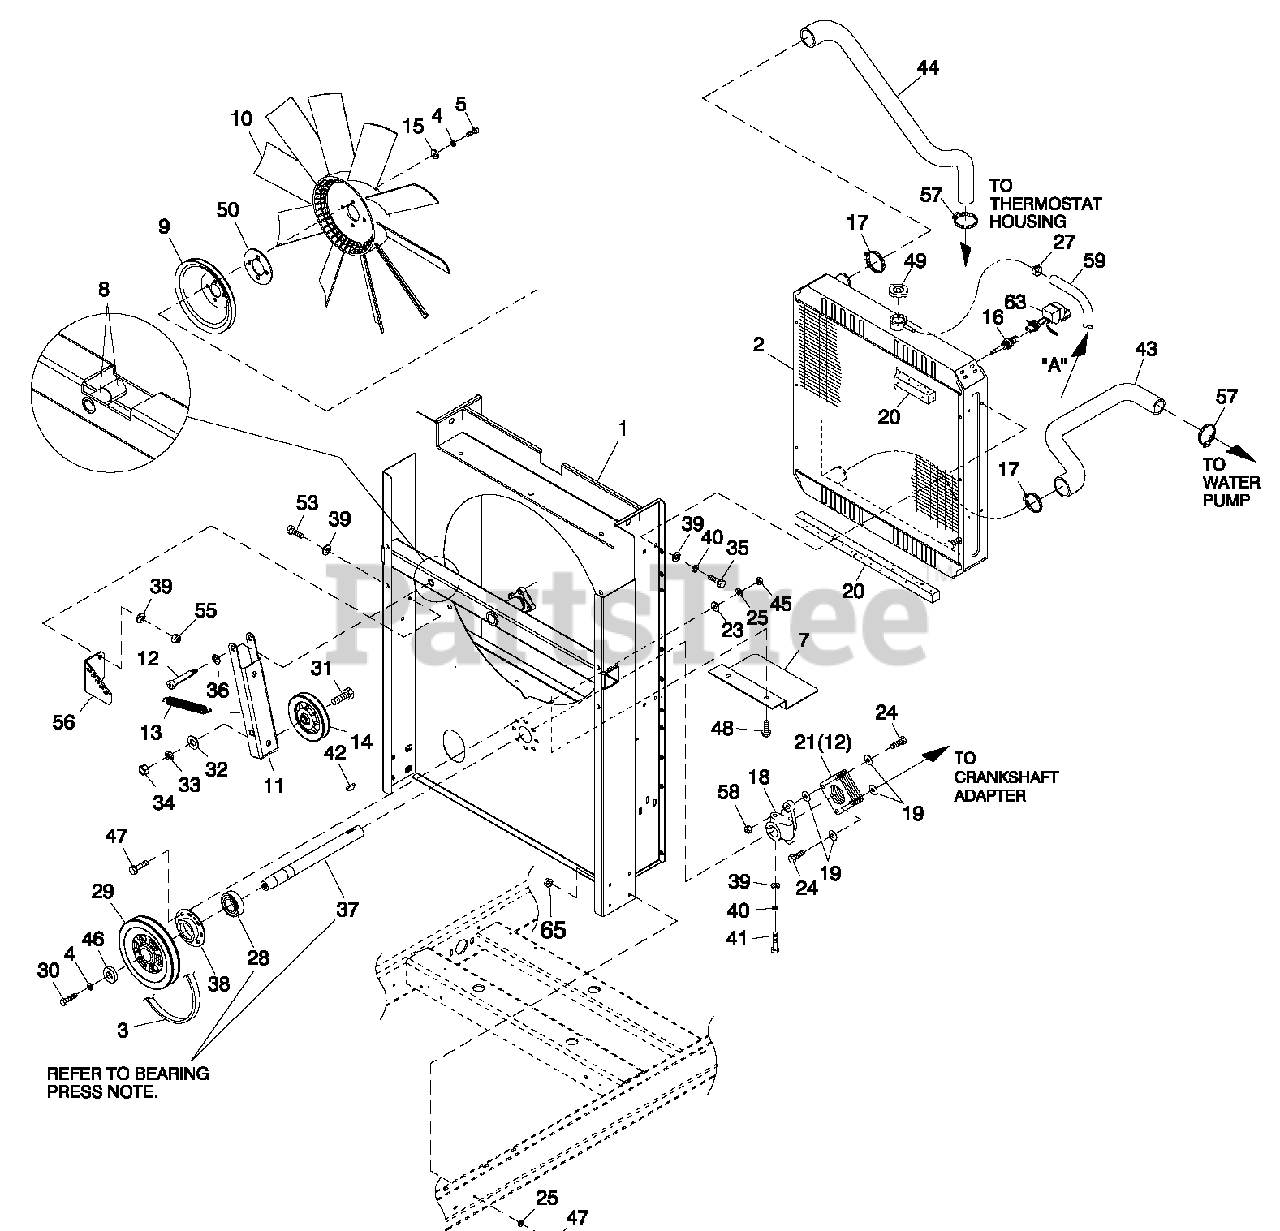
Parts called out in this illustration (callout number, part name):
1	WELDMENT RADIATOR SUPPORT C2
2	RADIATOR 598 X 568 X 49 CPL RH
3	V-BELT A58 (60IN O.C.) DDC S60
4	WASHER LOCK M10
5	SCREW HHC M10-1.5X 30 G10.9
7	SHIELD RADIATOR C4
8	BEARING SLEEVE 1/2/ X 3/4 X 1
9	PULLEY FAN V-GROOVE 9"
10	FAN COOL 22" D IA 10 BLADE LH
11	ARM BELTTENSIONER
12	SHOULDER BOLT 1/2 X 2-1/4"
13	SPRING TENSION CPL
14	PULLEY V-BELT 4" FLANGED
15	WASHER FLAT 3/8-M10 ZINC
16	PROBE COOLANT LEVEL 3/8 NPTF
17	CLAMP HOSE #28 1.32-2.25
18	HUB FLEX PLATE
19	WASHER FLEX (THIN)
20	TAPE FOAM 1 X 1 (26.75" LG)
21	DISK FLEX
23	WASHER FLAT 1/4-M6 ZINC
24	SCREW HHC 5/16-24X1.124
25	WASHER LOCK M6-1/4
28	BEARING #6205 2NSE C3 E SRI2 S
29	PULLEY 7.5" DIA MACHINED
30	SCREW HHC M10-1.5X 30 G8.8
31	SCREW HHC 1/2-13 X 2" G8
32	WASHER FLAT 1/2 ZINC
33	WASHER LOCK 1/2
34	NUT HEX 1/2-13 STEEL
35	SCREW HHFC M8-1.25X20W/M6
36	WASHER NYLON .50 X .87 X .06
37	SHAFT FAN DRIVE
38	RETAINER BEARING
39	WASHER FLAT 5/16-M8ZINC
40	WASHER LOCK M8-5/16
41	SCREW HHC M8-1.25X45C8.8
42	KEY WOODRUFF 4 X 19D
43	HOSE LOWER RADIATOR G2
44	HOSE UPPER RADIATOR G2 (USED WITH MANFLD P/N 0G0707)
45	NUT HEX M 6X 1 .0G 8Y E LC H R
46	SPACER .5 X 1.5 X .25 STL/ZINC
47	SCREW HHFC M6-1.0X20G8.8
48	SCREW THF M6-1 X 16 N WA Z/JS
49	CAP RADIATOR 13 PSI
50	SPACER CPL COOLING FAN 1/8"
53	SCREW HHC M8-1.25X20 C8.8
55	NUT HEX LOCK M8-1.25 NY INS
56	BRACKET TENSIONER SPRING
57	CLAMP HOSE #24 B1.06-2.00
58	NUT HEX LOCK 5/16-24 NY INS
63	ASSY PCB LCL SENSOR (USE WITH I/N 16, P/N 0H1827 ONLY)
64	TIE WRAP UL 7.4" X .19" BLK
